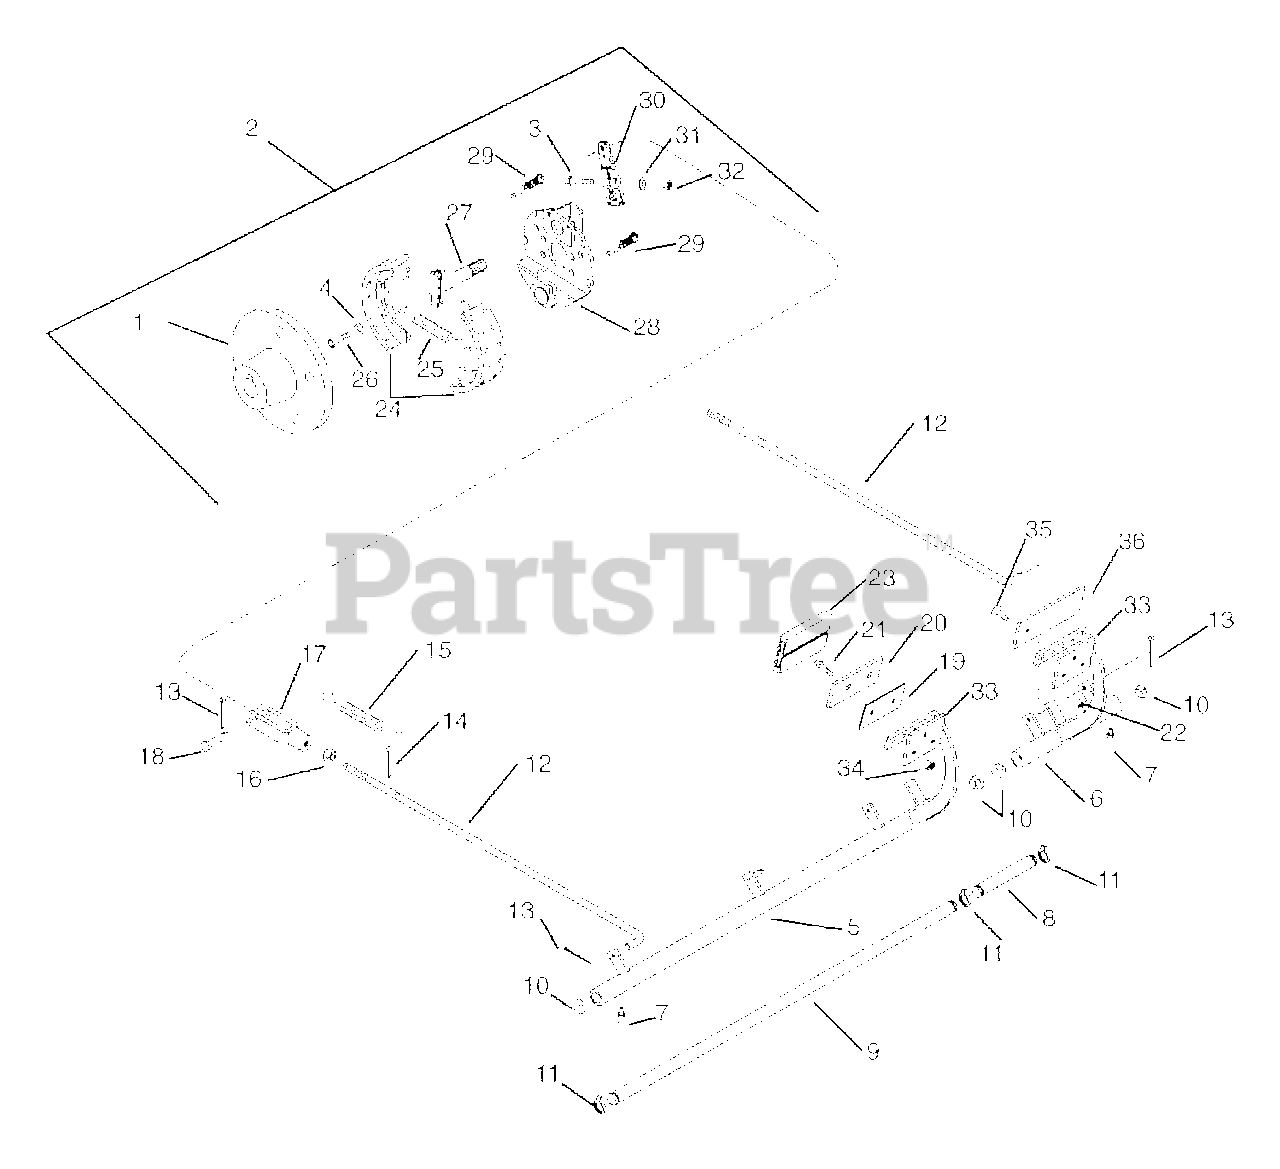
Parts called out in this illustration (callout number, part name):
1	Hub, Wheel
2	Brake, 7 x 1.75 Mechanical
3	Bolt-Hex, .31-24 x 1.75
4	Washer-Lock, .31 x .078
5	Weldment, Brake Pedal Right Hand
6	Weldment, Brake Pedal Left Hand
7	Fitting-Lube, .25-28 x .256
8	Shaft, Brake Pivot Short
9	Shaft, Brake Pivot Long
10	Bushing-Flange, .630 x 1.000 x .625
11	Ring Retaining External, .625 x .035
12	Rod, Brake
13	Pin-Cotter, .09 x .75
14	Pin-Cotter, .12 x .75
15	Spring-Tension, .091 x .500 x 5.500
16	Nut-,lam, .375-24
17	Clevis, .38-24 Adjustable
18	Pin-Clevis, .375 x .948
19	Plate, Brake
20	Pedal, Brake
21	Bolt-Round Head Square Neck .25-20 x 1.00
22	Nut-Lock-Control, .25-20
23	Pad, Pedal
24	Kit, Brake Shoe
25	Spring, Shoe Return
26	Hex Bolt, .31-18 x .75
27	Cam, Brake
28	Plate, Back
29	Spring, Shoe Ret Box
30	Arm, Cam Lever
31	Washer-Lock .313 x .078
32	Nut-Hex.312-24 Grade 2
33	Plate, Brake Lock Backing
34	Nut-Locking-Nylon .250-20 Grade 2
35	Screw-Machine .25-20 x 1.00
36	Arm, Brake Lock
